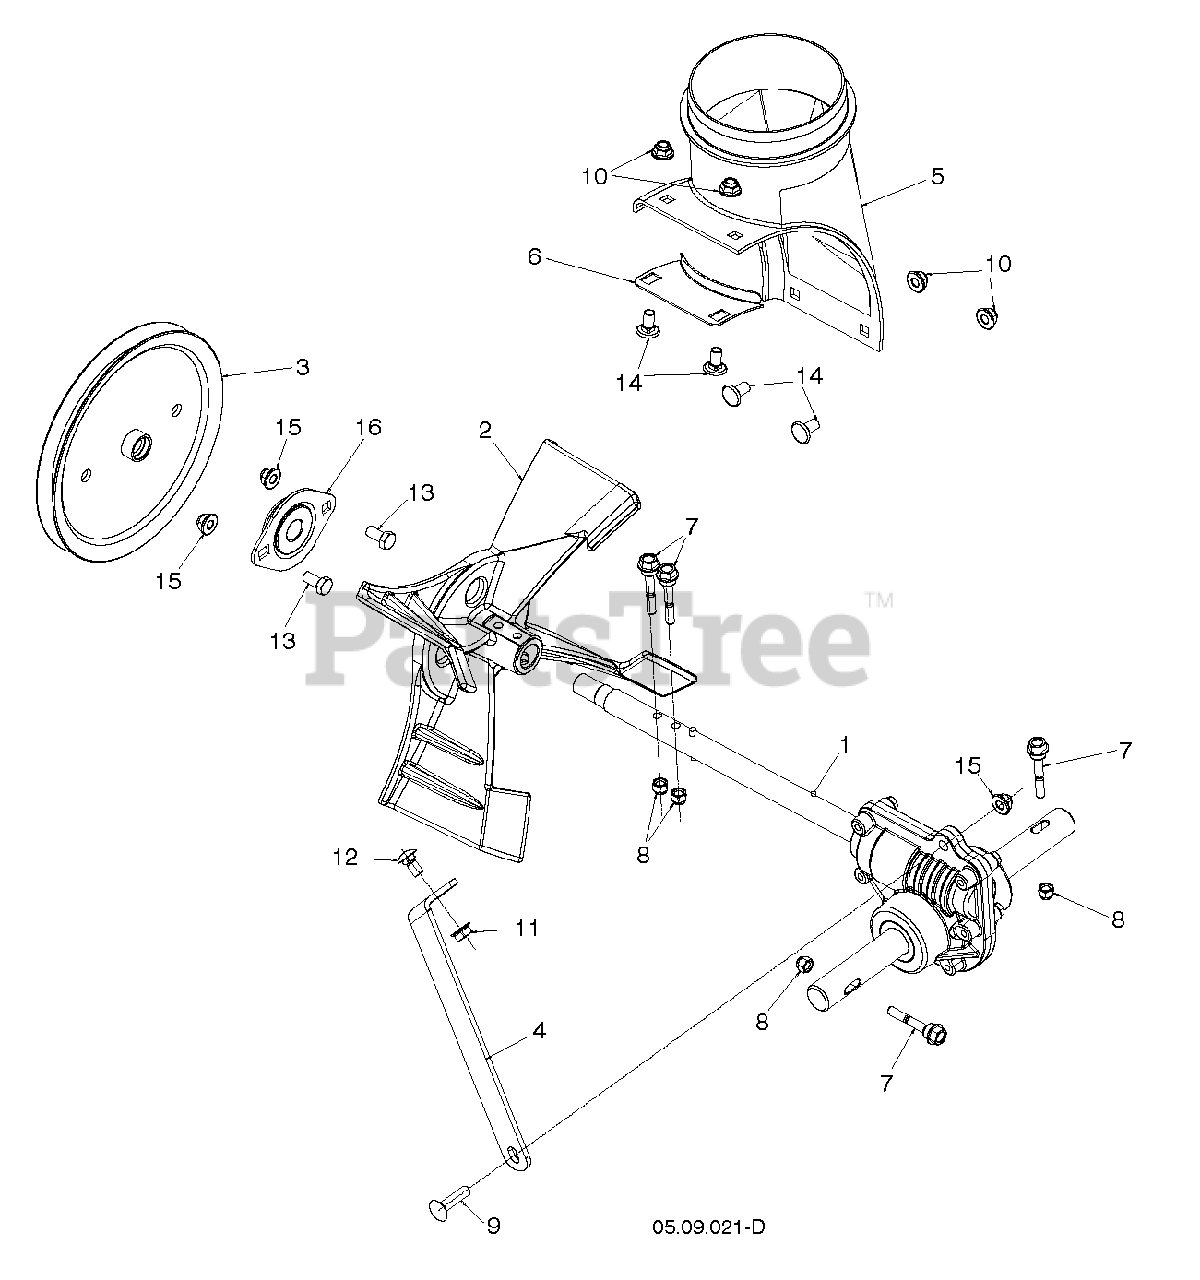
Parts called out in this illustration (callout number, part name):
1	GEAR BOX ASM CAST
2	IMPELLER CAST.IRON.12IN MS 417
3	PULLEY SCREW ON 7.9
4	SUPPORT.GEARBOX.LS.498
5	CHUTE.DISCHARGE.BASE
6	BRACKET, CORNER DISCHARGE
7	RP_SCREW.1/4-20 X 1-13/16 SHEA
8	LOCKNUT.NYLOC.1/4-20
9	BOLT.CARRIAGE.5/16-18
10	NUT HEX FLG NYLOCK BLK 5_16-1
11	NUT.LOCK.5/16-18
12	BOLT CAR BLK 5/16-18 X 5/8
13	BOLT, HEX HEAD 5/16-18
14	BOLT CARR WAFER BLK 5_16-18 X
15	NUTNYLOK.FLRANGE.5/16-18
16	BEARING FLANGE
